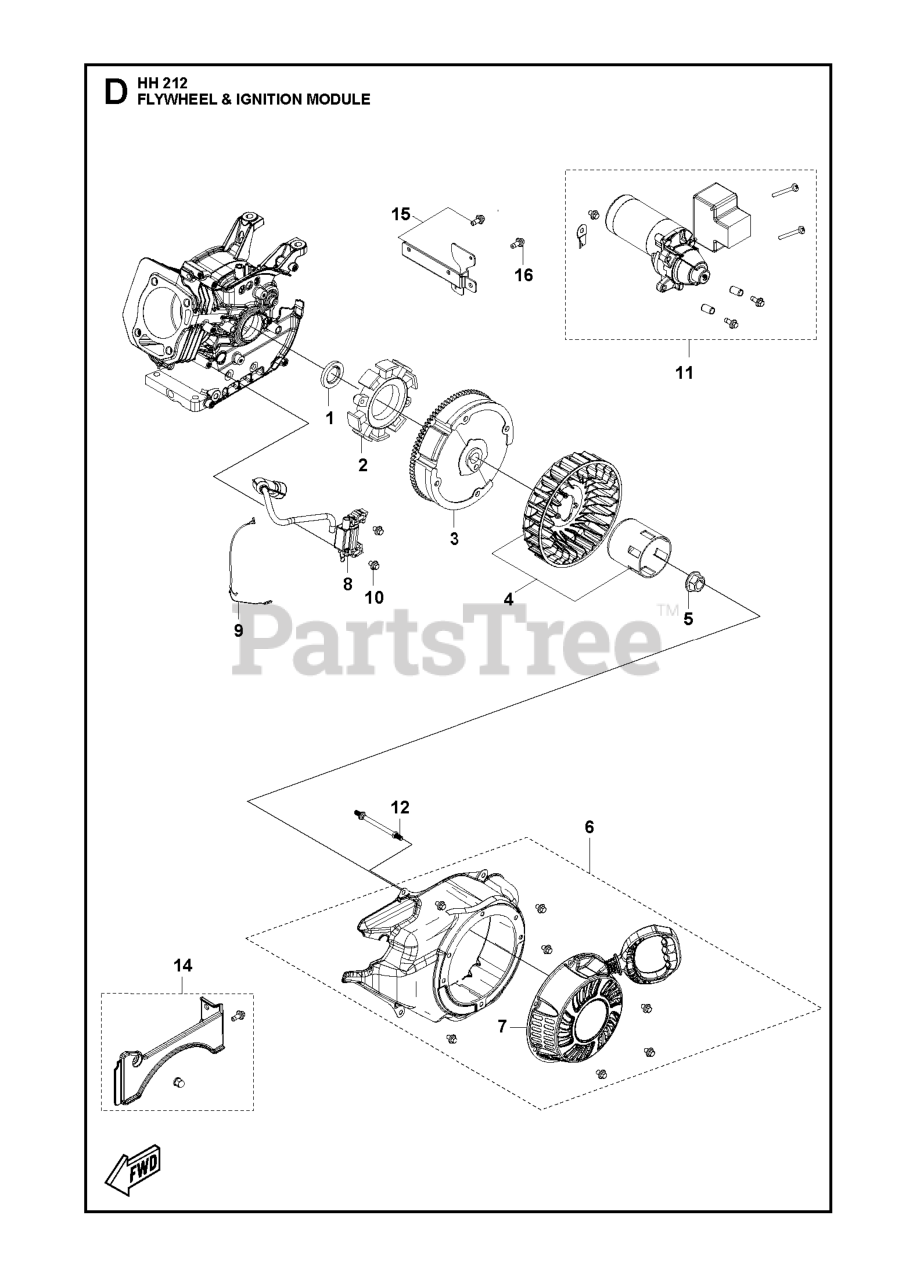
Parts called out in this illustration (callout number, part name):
1	SEAL OIL SEAL
2	COIL CHARGE COIL
4	IMPELLER KIT
6	STARTER RECOIL STARTER
7	STARTER ASSY STARTER ASSY AND
8	COIL CHARGE COIL SUBASSEMBLY
9	WIRE IGNITION COIL STOP ENGINE
10	BOLT
11	STARTER MOTOR
14	GUARD FRONT GUARD
15	SUPPORT KIT
16	BOLT
